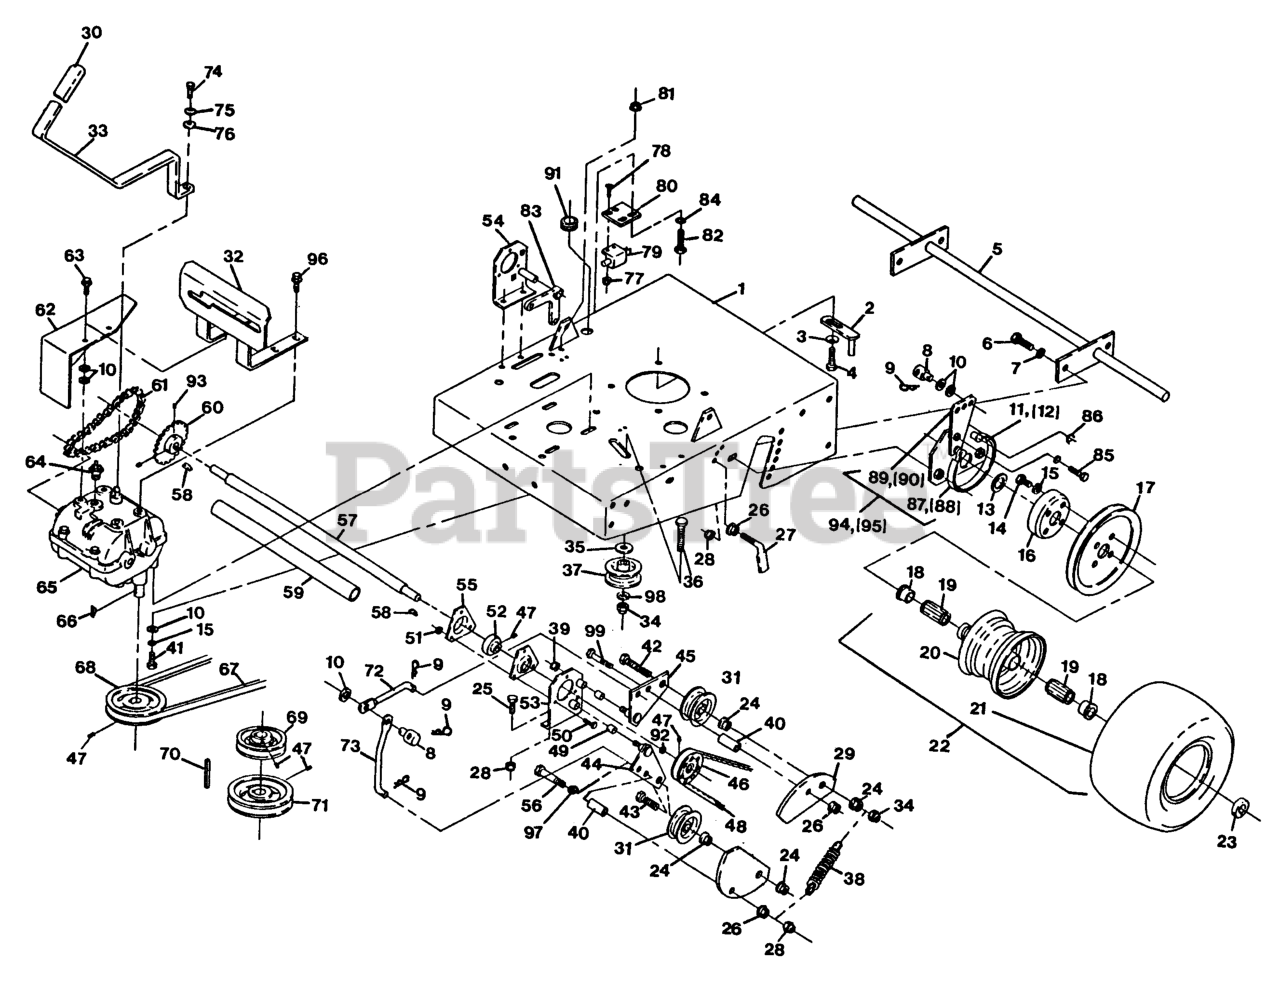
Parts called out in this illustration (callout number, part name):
2	GUIDE - BELT, 32
3	WASHER-SPRING
8	SWIVEL,SHORT ADJUSTING
9	PIN-COTTER
13	WASHER-FLAT
15	WASHER-LOCK
17	SHEAVE,SPLIT STEEL 9 B
19	BEARING,ROLLER
23	COLLAR,LOCKING 7/8
30	GRIP-LEVER
31	PULLEY,IDLER
37	IDLER,PULLEY
38	SPRING-IDLER
39	NUTTORQUE ZKPLT
44	ARM - IDLER
45	ARM - IDLER
47	SCREW-SET
48	BELT,COG
57	JACKSHAFT
61	CHAIN,DRIVE
64	SWITCH-START, NEUTRAL
67	BELT,TRANSMISSION
70	KEY,MACH 1/4X1/4X2-5/8
71	SHEAVE,BLADE DRIVE
72	LINKAGE,UPPR CALIPERPLT
73	LINKAGE,LOWER CALIPER RH
75	WASHER-SPRING
79	SWITCH-OPEN, NORMALLY
80	BRACKET,SAFETY SWITCH
83	BELLCRANK
86	PIN-LEVER, DRIVE
89	WLD,BRAKE LEVER RH
91	GROMMET
93	SCREW-SET
94	ASM,BRAKE LH
95	ASM,BRAKE RH
97	WASHER-LOCK
